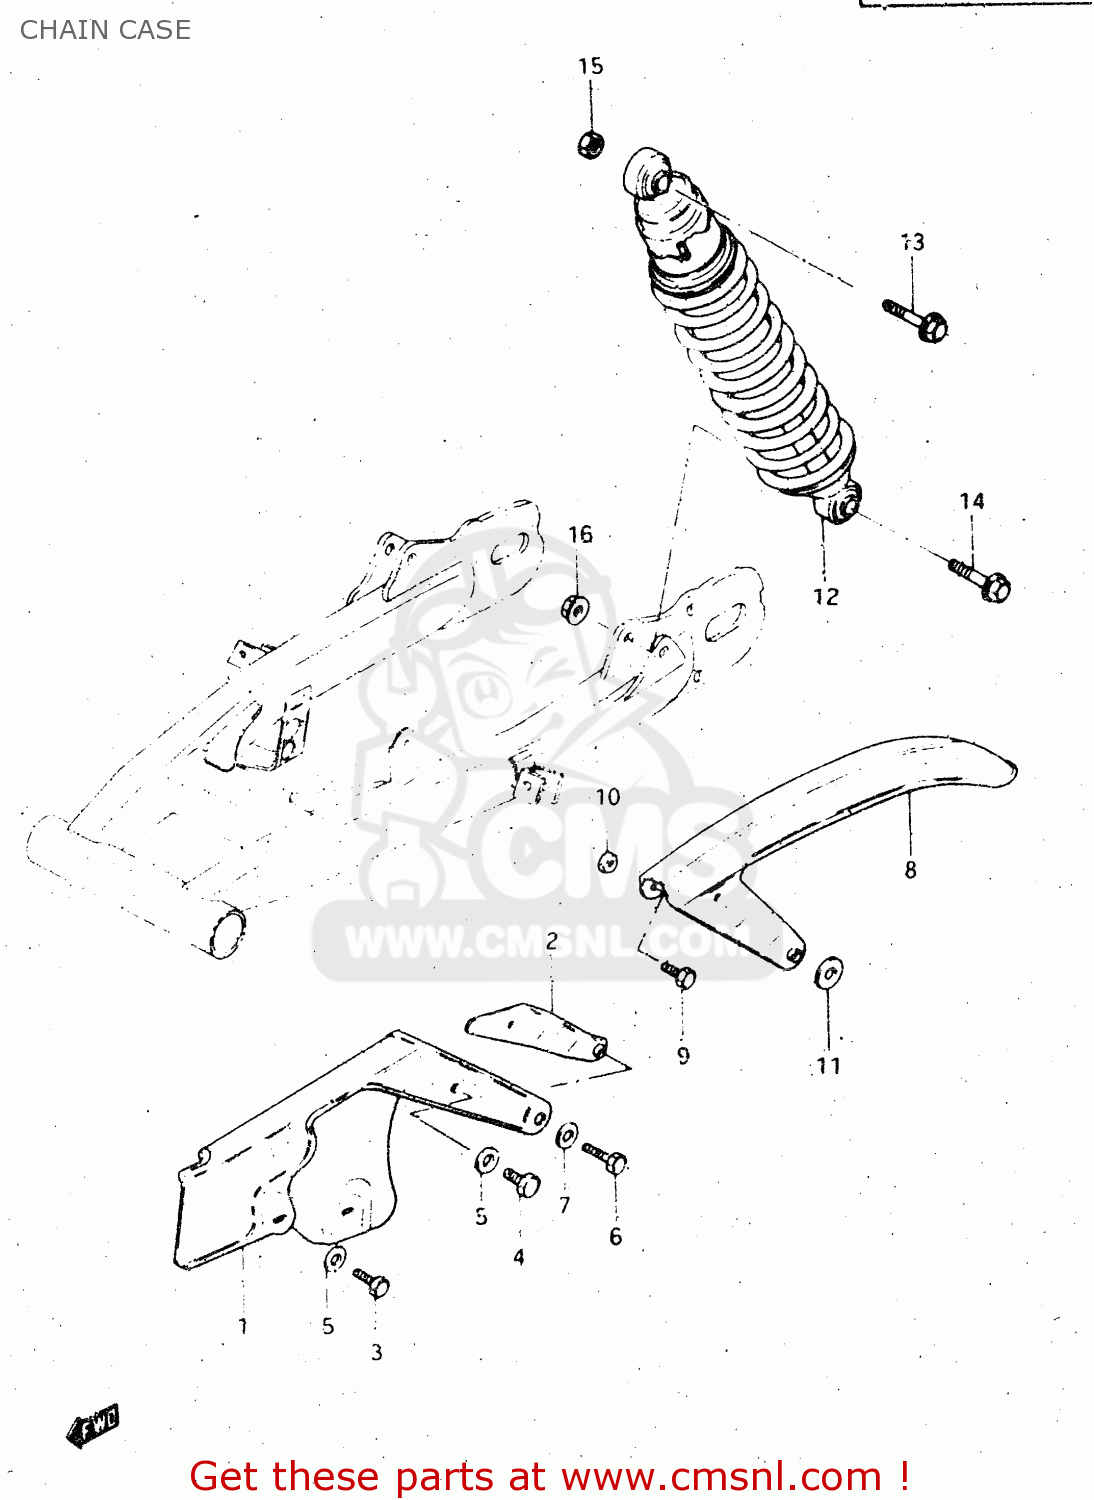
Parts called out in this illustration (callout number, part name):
1	CASE,CHAIN
2	REINFORCEMENT,CHAIN CASE
3	BOLT
4	BOLT 6X8
5	WASHER,LOCK
6	BOLT
7	WASHER
8	CHAIN CASE, END
9	BOLT
10	NUT
11	WASHER,LOCK
12	ABSORBER ASSEMBLY,REAR SHOCK
13	BOLT(10X40)
14	BOLT(10X50)
15	NUT
16	NUT
